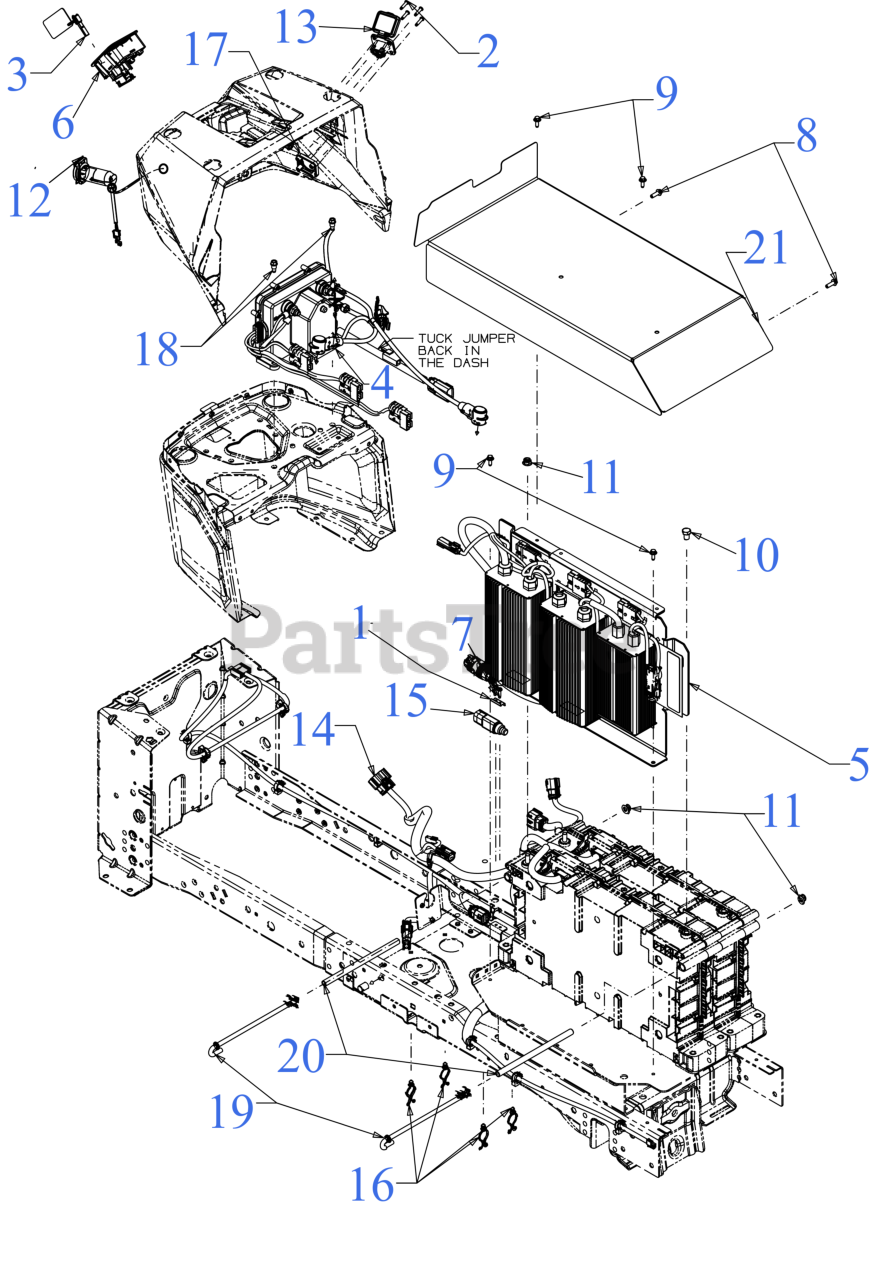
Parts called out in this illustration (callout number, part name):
1	PLATE-SWITCH
2	SCREW, #8-16X.750 PH
3	MAGNETIC KEY
4	PDM HOUSING ASSEMBLY
5	CONTROL PANEL
6	VCM SWITCH (UL G2)
8	SCREW 1/4 x .750
9	SCREW M6-1 x .625
10	SCREW 3/8-24 x .50" GR5 STD
11	FLANGE LOCK NUT 5/16-18
12	USB RECEPTACLE (12V W/JUMPER)
13	CHARGER PORT HARNESS (8-PIN)
14	HARNESS (VCM/PDM/GEN2)
15	SEALED PLUNGER SWITCH
16	TWIST LOCK CLIP
17	CHARGING PORT ADAPTER
18	SHOULDER SCREW
19	BATTERY ROD
20	SPACER- .322" x .438" x 7.71"
21	BATTERY COVER BRACKET
